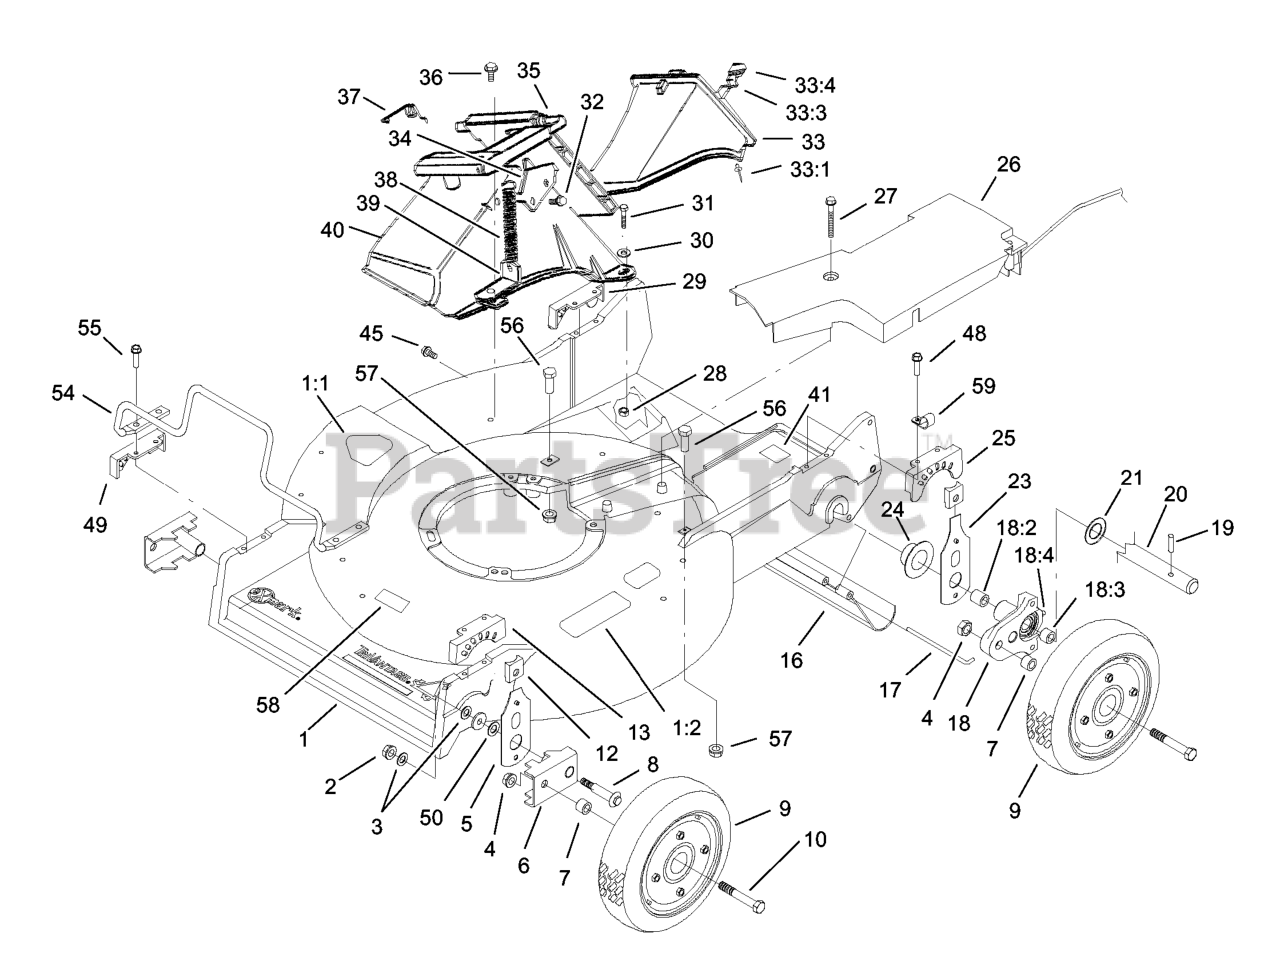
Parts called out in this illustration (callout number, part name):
1:1	DECAL-DANGER
1:2	DECAL-WARNING
2	NUT-LOCK
4	NUT-LOCK, CONE
5	FRONT SPRING ARM ASM
6	ARM-PIVOT, FRONT
7	SPACER-WHEEL
10	BOLT-CARR
12	KNOB-ARM
13	QUADRANT-FRONT, LH
17	ROD-SHIELD
18	PIVOT ARM ASM
18:2	BUSHING
18:3	BUSHING
18:4	FITTING-GREASE
19	PIN-SPIROL
20	SHAFT-AXLE, REAR
21	WASHER-PLAIN
23	REAR SPRING ARM ASM
24	CAP-END
25	QUADRANT-REAR, LH
26	COVER-BELT
27	SCREW-HWH
28	NUT-LOCK, NI
29	QUADRANT-REAR, RH
30	WASHER-FLAT
31	SCREW-HH
32	SCREW-PLASTITE
33	DISCHARGE PLUG ASM
33:1	RIVET-HEAD, FLAT
33:3	LATCH-PLUG, DISCHARGE
33:4	GRIP-LATCH
34	LATCH-PLATE
35	DISCHARGE DOOR ASM
36	SCREW-HWH
37	RETAINER-DOOR
38	SPRING-DOOR
39	BRACKET-SPRING
40	TUNNEL-DISCHARGE
41	LABEL-GREASE, HP
45	SCREW AND WASHER ASM
48	SCREW-HWHTF
49	QUADRANT-FRONT, RH
50	WASHER-THRUST
54	GUARD-ENGINE
55	SCREW-HWHTF
56	SCREW-HH
57	NUT-LOCK, NI
58	DECAL-BLADE
59	CLIP-CLOSED, INSULATED
